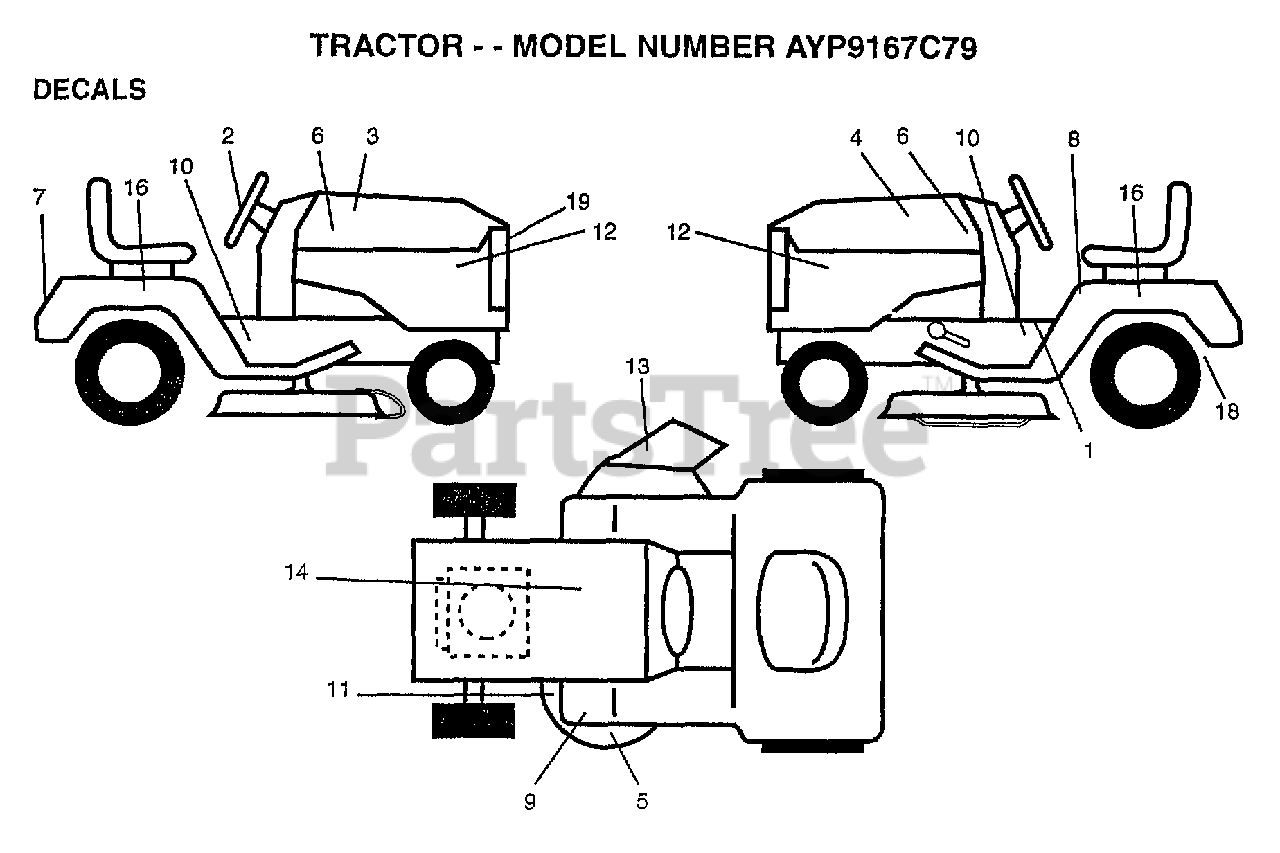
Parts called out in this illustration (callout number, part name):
1	"DECAL INST,SADDLE"
2	DECAL STEER WHL
3	DECAL HOOD RH
4	DECAL HOOD LH
5	DECAL DECK WIZ +
6	NAMEPLATE.HD.WIZA
8	"DECAL DANGER,FEND"
10	"DECAL.CHASSIS.42"""
11	DECAL
12	"DECAL PANEL,SIDE"
13	DECAL DECK MULCH
14	DECAL.BATRY.3-3908
16	DECAL.FENDER.WIZ
18	DECAL DRAWBAR LH
19	DECAL.LENS.WIZARD
